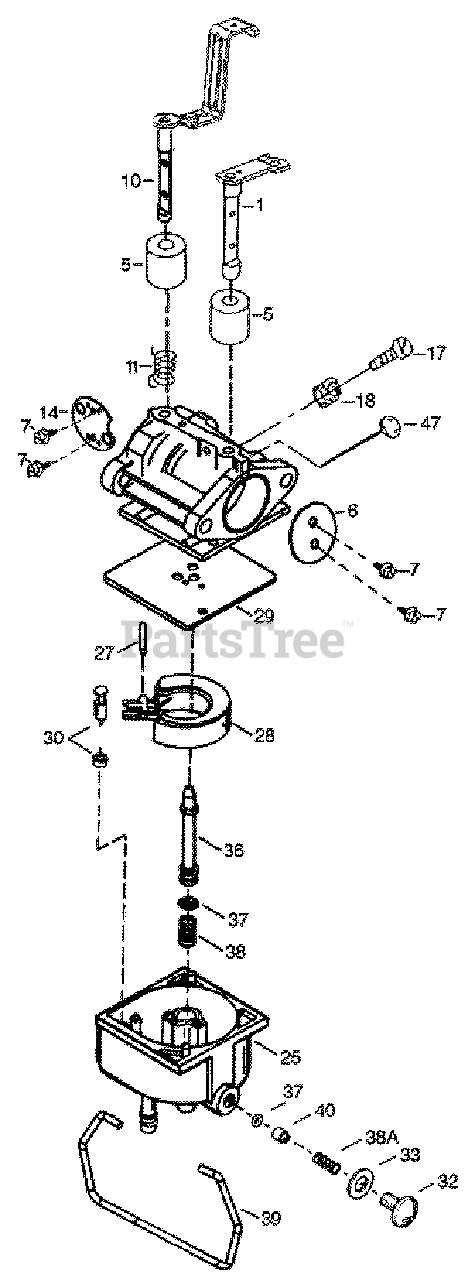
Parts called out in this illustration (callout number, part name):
1	Throttle Shaft & Lever Assembly
6	Throttle Shutter
7	Throttle & Choke Shutter Screws
10	Choke Shaft & Lever Assembly
11	Choke Return Spring
14	Choke Shutter
17	Throttle Crack Screw/Idle Speed Screw
18	Tension Spring
25	Float Bowl Assembly
25A	Float Bowl Repair Kit
29	Float Bowl to Body Gasket
30	Inlet Needle & Seat
32	Bowl Drain Screw
33	Bowl Drain Washer
36	Main Nozzle Tube
37	O-ring
38	Spring, Main Nozzle Tube
39	Float Bowl Retainer
40	Main Fuel Jet
47	Welch Plug, Idle Mixing Well
